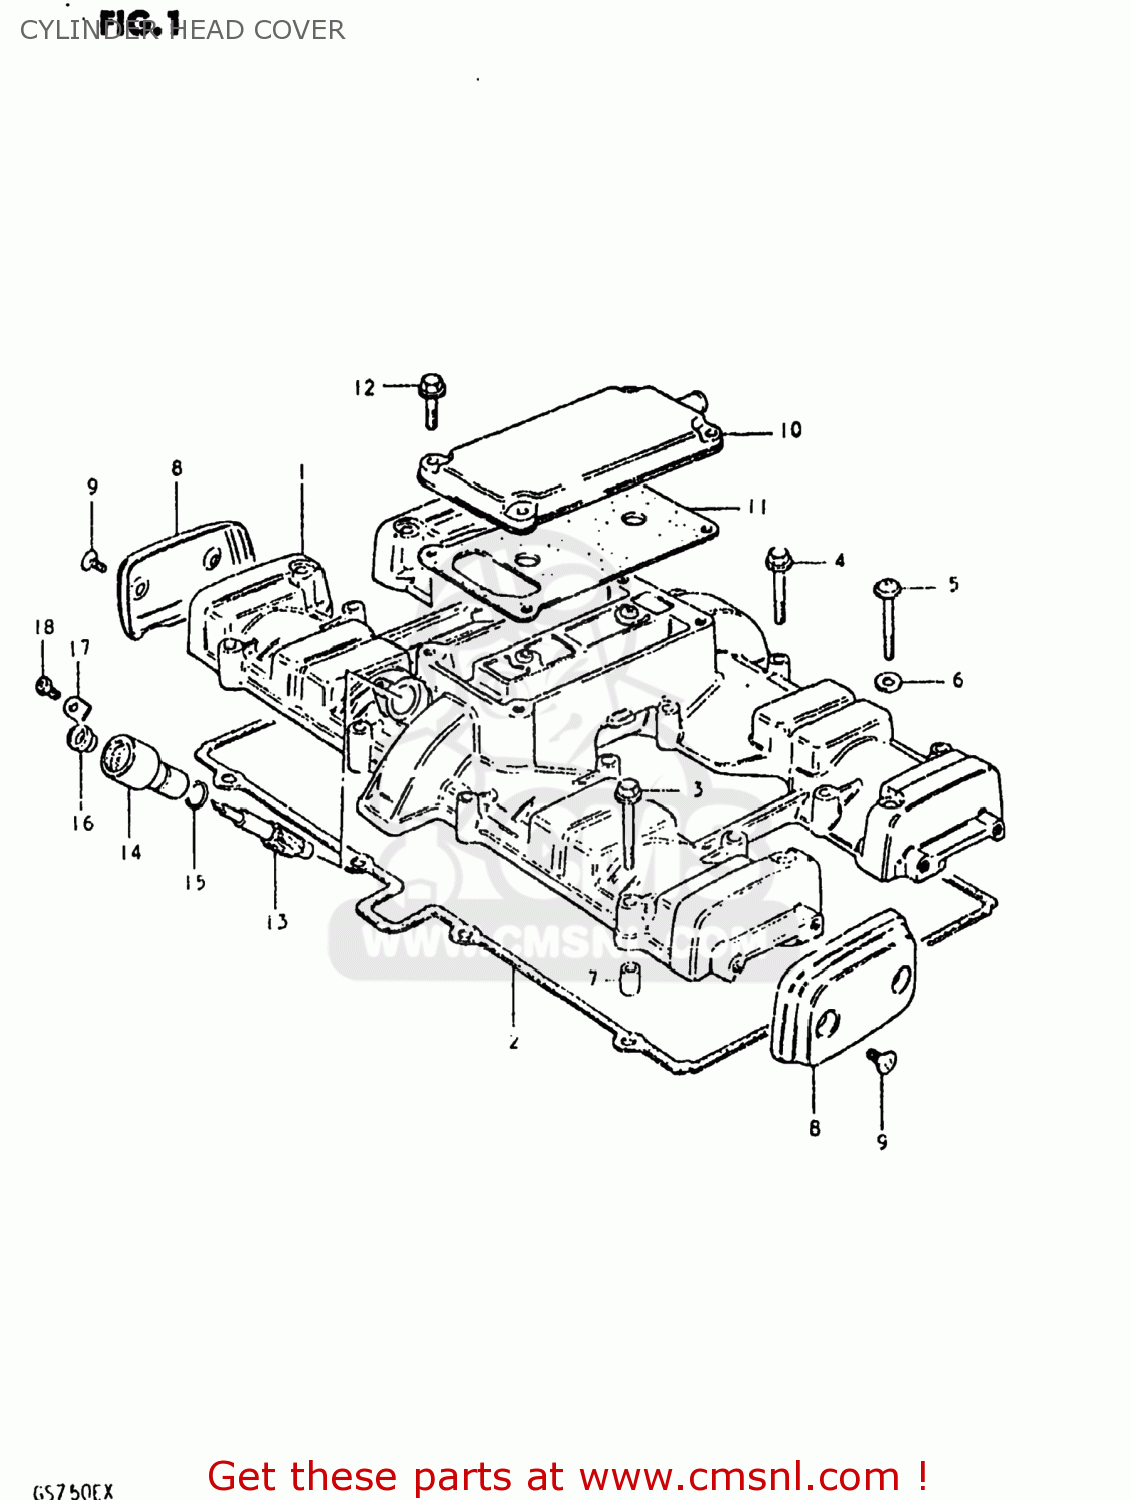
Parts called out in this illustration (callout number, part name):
1	COVER,CYLINDER HEAD
2	GASKET,CYLINDER HEAD COVER (MCA)
3	BOLT
4	BOLT 6X35
5	SCREW 6X40
6	GASKET (NAS)
7	PIN(6.2X8X11)
8	CAP,CYLINDER HEAD COVER
9	SCREW 5X12
10	COVER,BREATHER
11	GASKET (MCA)
12	BOLT,REAR
13	GEAR,TACHOMETER DRIVEN
14	SLEEVE,TACHOMETER DRIVE
15	SEAL,TACHOMETER DRIVEN
16	SEAL,OIL(5X12X8)
17	PLATE,TACH DRIVE GEAR SLEEVE
18	SCREW(5X12)
